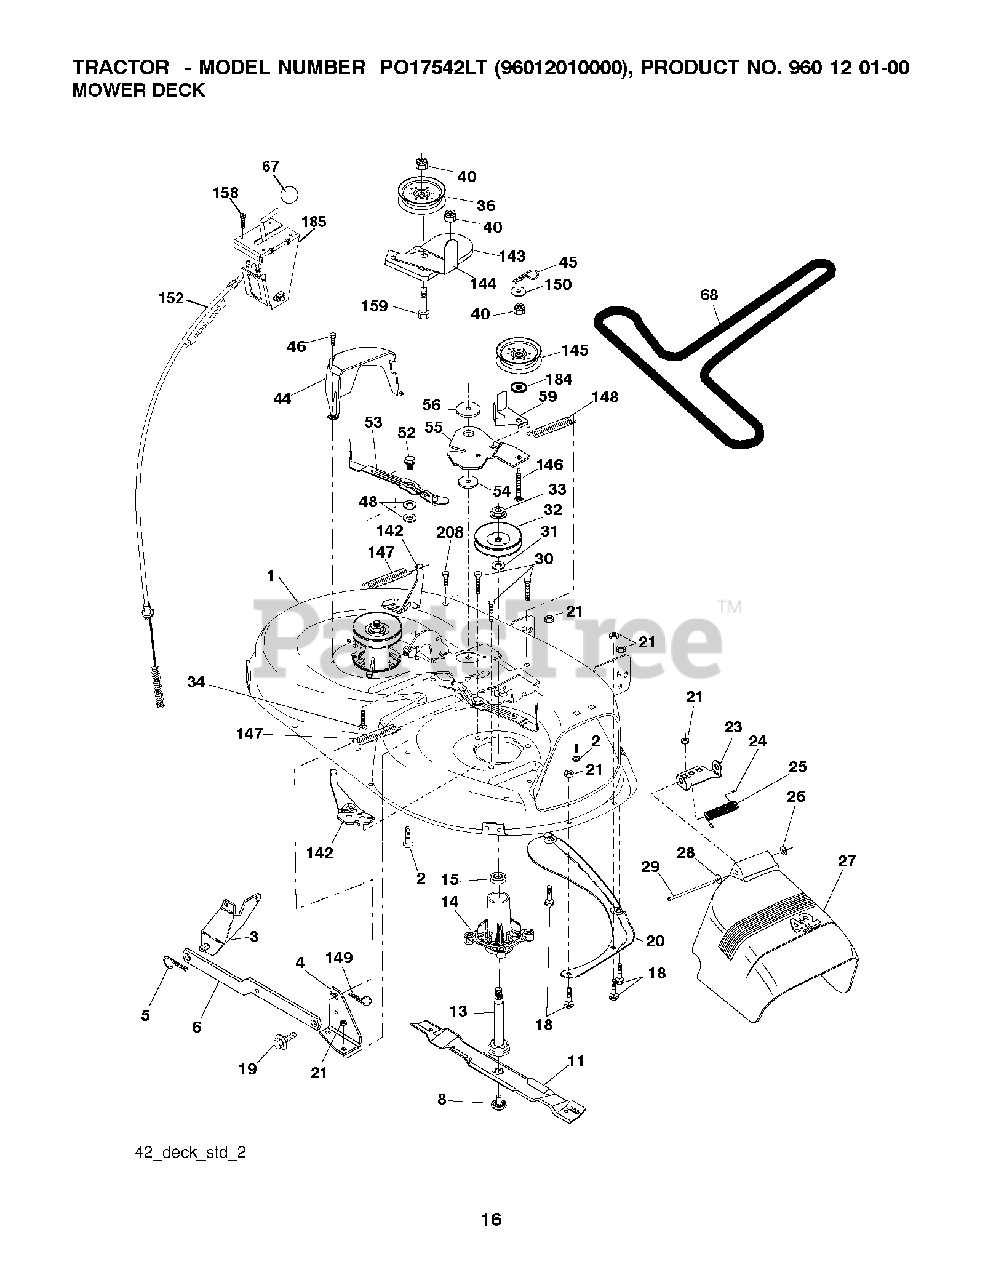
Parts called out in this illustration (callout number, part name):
2	BOLT
3	BRKT ASM SWAY BAR
4	BRACKET SWAY BAR 42" DECK
5	RETAINER-SPRNG RB
6	BAR SWAY DECK
8	BOLT.WASHER.ASM.7/16-2
11	42" HI-LIFT BLADE
11	BLADE.42".MULCH
11	BLADE.42"MULCH.PREMIUM
11	BLADE.42SP"3N1.
11	BLADE.42SP"3N1
13	SHAFT.ASM.MDRL.N/GREASE.38
14	HOUSING.MANDREL.4PT.
18	BOLT
19	BOLT SHD 5/16-18
20	BAFFLE.VORTEX
21	LOCKNUT
23	BRKT, DEFL. MOWER
24	CAP-SLEEVE LT
25	SPRING TORSION
26	NUT PUSH M
27	SHIELD DEFLECTOR
28	WASHER
29	ROD.HINGE
30	SCREW, WASHER HEAD
31	WASHER.SPACER.MANDREL
32	PULLEY/MANDREL
33	NUT.FLANGE.LOCK.TOP
34	BOLT.3/8-16X1.50
36	FLAT IDLER PULLEY
40	NUT LOCK FLG 3/8-16 UNC
44	GUARD MANDREL LH BLACK
45	RETAINER M
46	SCREW.1/4-20X5/8
52	BOLT.SHOULDER.5/16-18
53	ARM BRAKE ASSY
55	ARM IDLER 42" MOWER LT/YT
56	SPACER.RETAINER.MOWER
59	GUARD, BELT
67	KNOB T (3/8 HOLE)
68	BELT V SECONDARY
142	ANCHOR SPRING BRAKE MOWER
143	BRACKET, ARM IDLER
144	KEEPER.BELT.42".CLUTCH.CABLE
145	PULLEY
146	BOLT, CARRIAGE IDLER BLACK
147	SPRING EXTENSION
148	IDLER RETURN SPRING
149	SPRING.RETAINER.YELLOW.ZINC
150	WASHER LT
152	CLUTCH.CABLE.ASM/42"MOWER
158	SCREW
159	BOLT
184	WASHER
185	HEAD ASM. CABLE CLUTCH
208	SCREW 3/8-16X1/2
